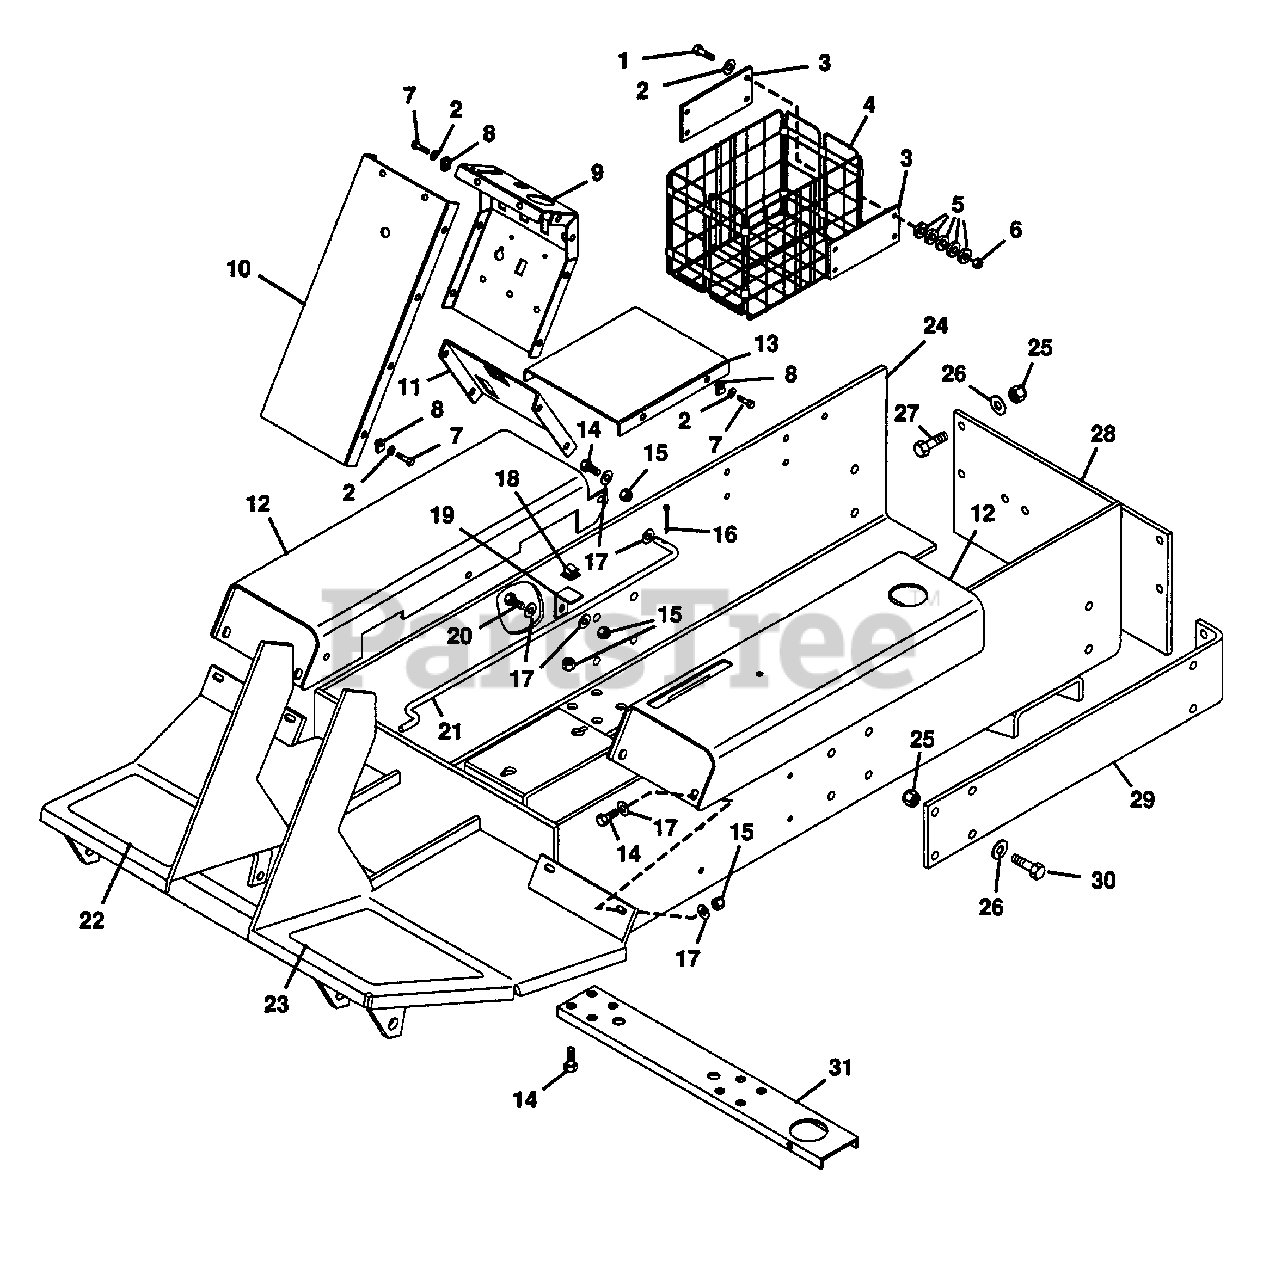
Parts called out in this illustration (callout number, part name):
1	Bolt, Hex 1/4-20x1.50
2	Washer, Flat .281x.625x.065
3	Strap, Basket
4	Basket
5	Washer, Friction
6	Nut, Lock 1/4-20
7	Screw, Machine 1/4-20 PHD
8	Nut, Retainer
9	Panel, Instrument Silk Screen
10	Panel, Front Silk Screen
11	Panel, Brake Lock Silk Screen
12	Fender, R.H. Silk Screen
12	Fender, L.H. Silk Screen
13	Plate, Access Silk Screen
14	Bolt, Hex 3/8-16x.875
15	Nut, Lock 3/8-16
16	Pin, Cotter .094x.75
17	Washer, Flat .406x.812x.065
18	Clip, Wire
19	Bracket, Stay Rod
20	Bolt, Hex 3/8-16x1.00
21	Rod, Stay
22	Cover, R.H. Foot
23	Cover, L.H. Foot
24	Weldment, Frame
25	Nut, Lock 1/2-13
26	Washer, Flat .531x1.062x.095
27	Bolt, Hex 1/2-13x1.50
28	Plate, Bumper
29	Bumper
30	Bolt, Hex 1/2-13x1.25
31	Brace, Frame
